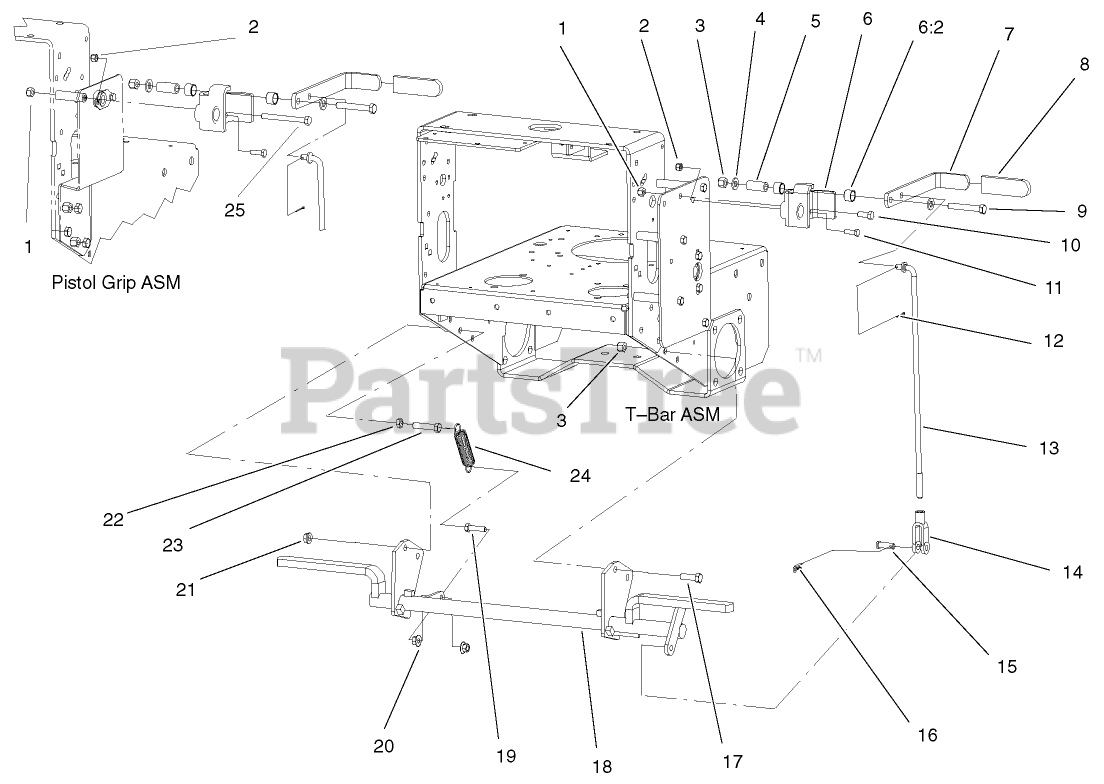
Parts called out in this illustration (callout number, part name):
1	NUT-LOCK, NI
2	NUT-LOCK, NI
3	NUT-LOCK, NI
4	WASHER-FLAT
5	BUSHING-PIVOT
6	BRACKET ASM
6:2	SLEEVE-BUSHING
7	HANDLE-PARKING BRAKE
8	GRIP-LEVER
9	SCREW-HH
10	SCREW-HH
11	SCREW-HH
12	PIN-COTTER
13	ROD-LINK
14	YOKE-LINKAGE, BRAKE
15	PIN-CLEVIS
16	PIN-COTTER
17	SCREW-HH
18	BRAKE ASM
19	SCREW-HH
20	NUT-HF
21	NUT-HHF, WHIZ
22	NUT-JAM
23	SCREW-HH
24	SPRING-IDLER
25	SCREW-HH
